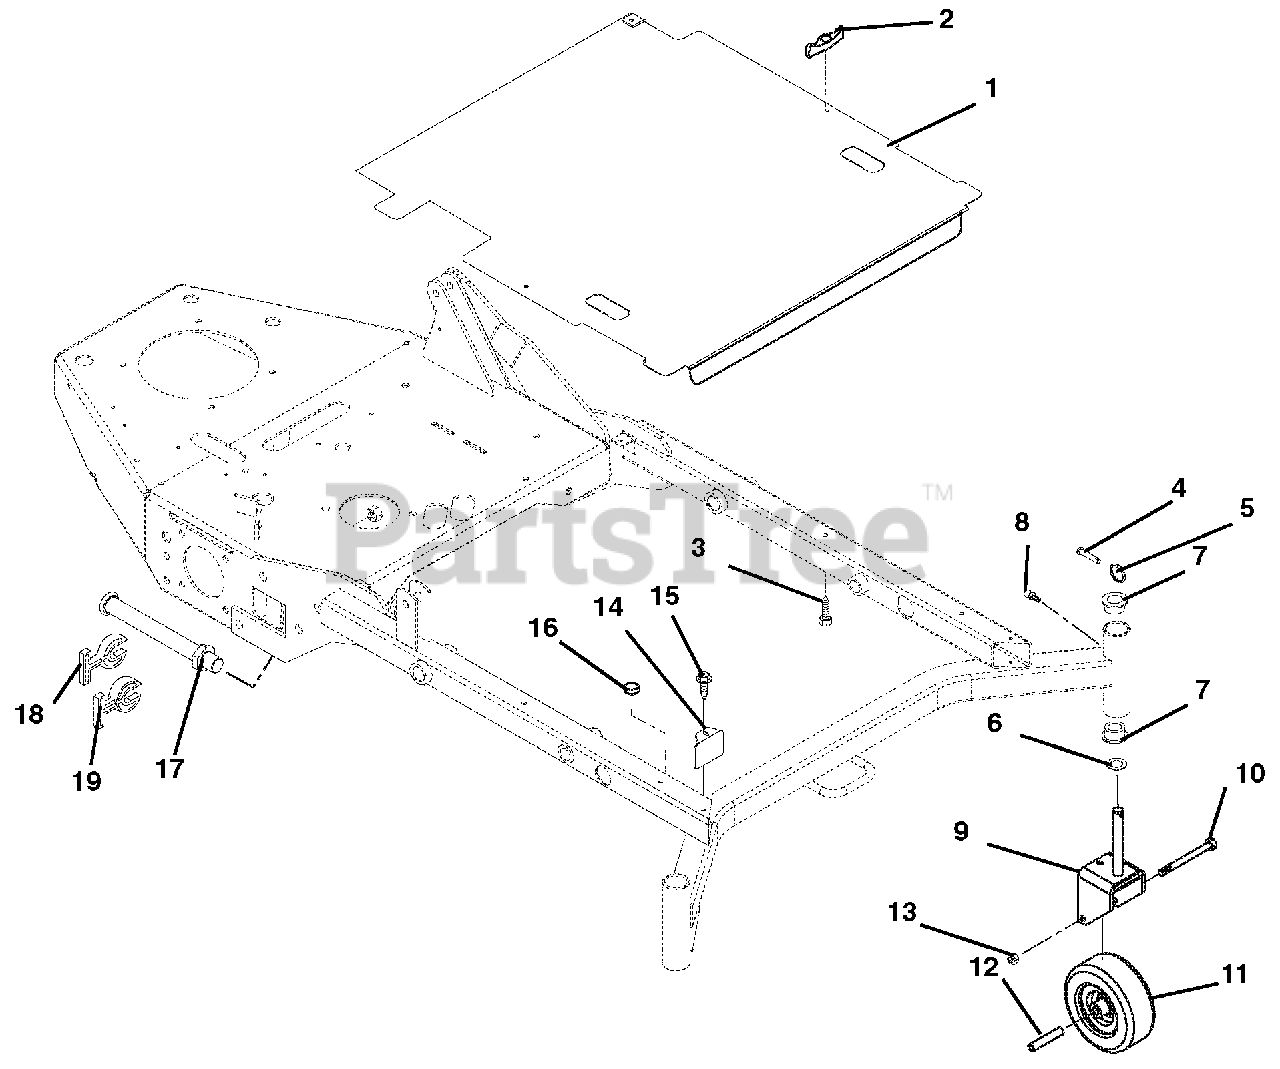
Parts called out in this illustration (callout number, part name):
1	Cover, Mower Deck
2	Knob, Wing .31-18
3	Bolt, Rib Neck .31-18 x 2.50
4	Pin, Clevis .31 x 2.62 Grade 5
5	Ring, Retaining-External 1.062 x 1.25
6	Washer, Hardened-Thrust 1.00 x 1.55 x .03
7	Bushing, Flange 1.020 x 1.385 x .75 x 1.75 Nylon
8	Fitting, Lube .25-28 x .256
9	Weldment, Caster Fork
10	Bolt, Hex .50-13 x 5.50 Grade 5
11	Wheel Assembly 9.00 x 3.50
12	Bearing .532 x .750 x 4.06
13	Nut, Locking-Top-Flange .50-13
14	Cover, Mower Tube
15	Screw, Tapping .25-20 x .50 Hex Washer Head
18	Stop, Cylinder .34 Thick
19	Stop, Cylinder .680 Thick
